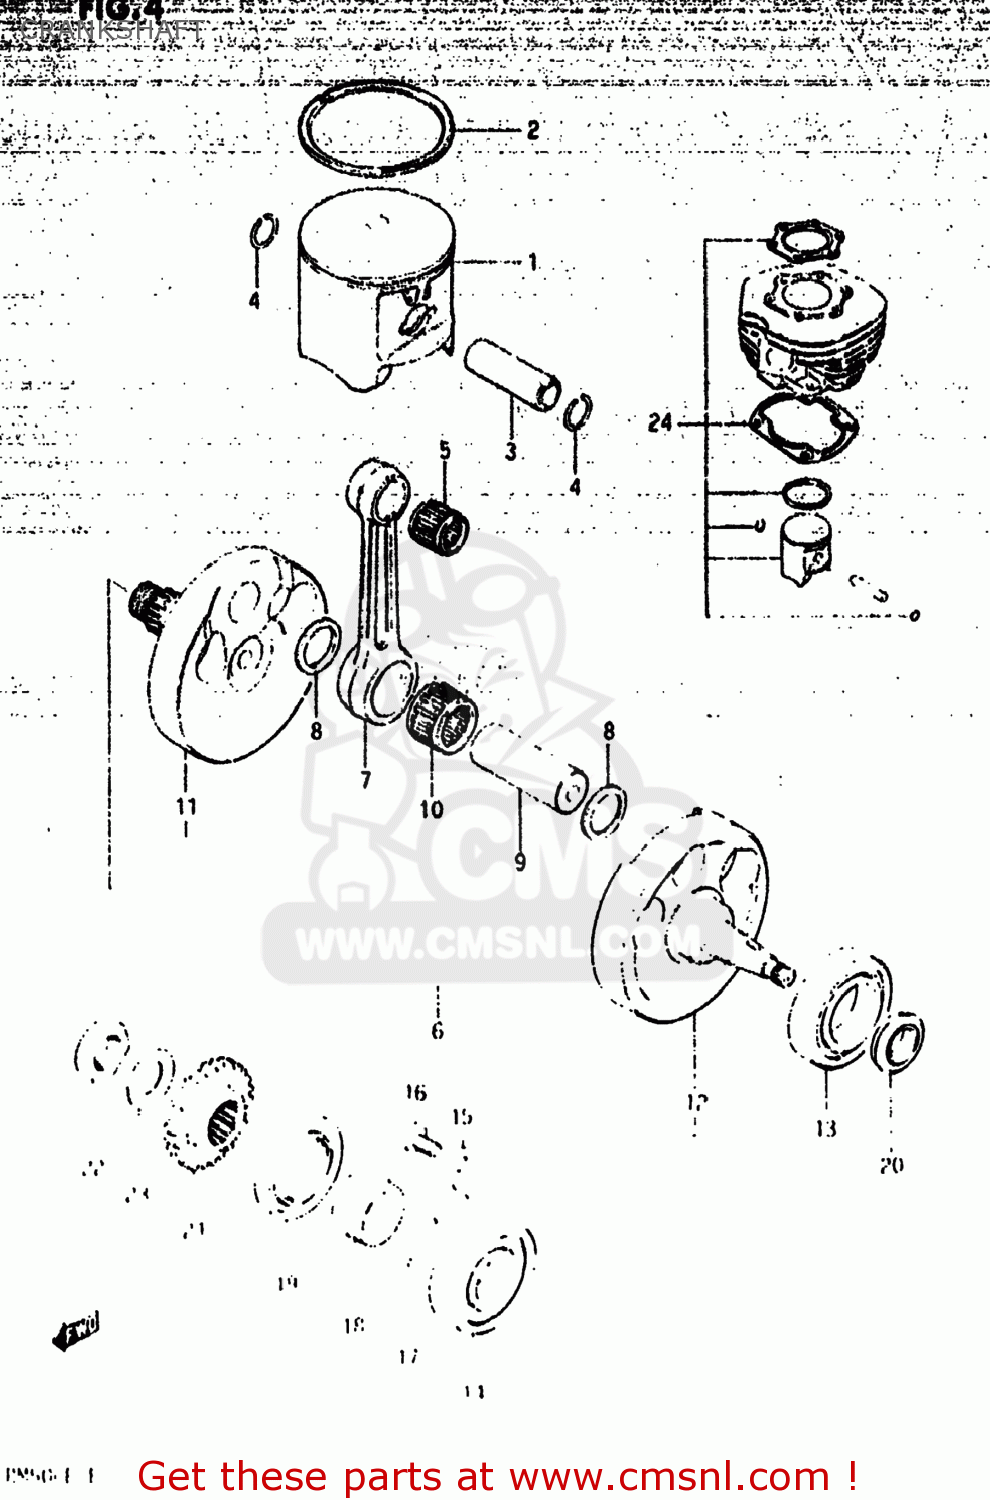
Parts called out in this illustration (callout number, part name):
1	PISTON
2	RING,PISTON
3	PIN,PISTON (18MM)
4	CIRCLIP
5	BEARING(18X23X22)
6	CRANKSHAFT ASSEMBLY
7	ROD,CONNECTING
8	WASHER(26X32X1.5)
9	PIN,CRANK
10	ROLLER BEARING (26X33X2
11	CRANKSHAFT,RIGHT
12	CRANKSHAFT,LEFT
13	BEARING
14	BEARING
15	PLATE,CRANKSHAFT OIL S
16	SCREW
17	O RING(D:2.4,ID:27.7)
18	SPACER,PRIMARY DRIVE GEAR
19	SEAL,OIL(37X62X9)
20	SEAL,OIL(19.6X37X8)
21	GEAR,PRIMARY DRIVE
22	NUT (20MM)
23	WASHER
24	PISTON SET
